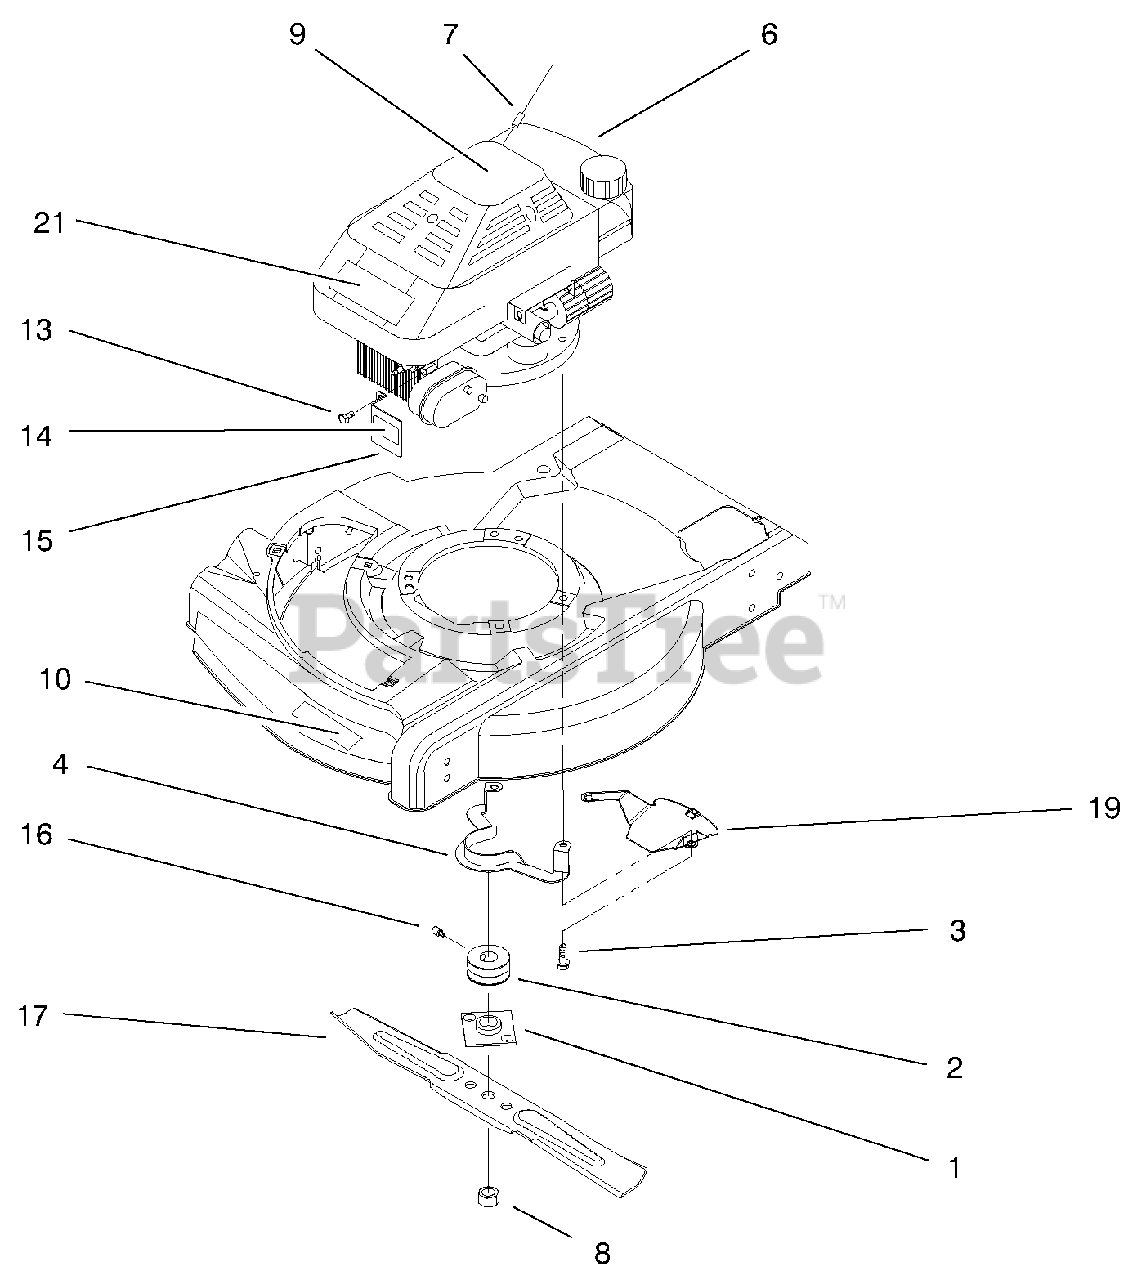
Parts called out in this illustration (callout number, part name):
1	ASM-Plate & Collar
2	Pulley-Engine
3	Screw-Engine Mount
4	Guide-Belt
5	Decal-Oil Instruction
6	ASM-Engine
7	Rope-Stop
8	Nut-Blade
9	Decal-Shroud
10	Decal-Deck
14	Decal-Hot Surface
15	Guard-Muffler
16	Screw-Set
17	Blade-21" Whirl
19	Shield-Grass
21	Applique
